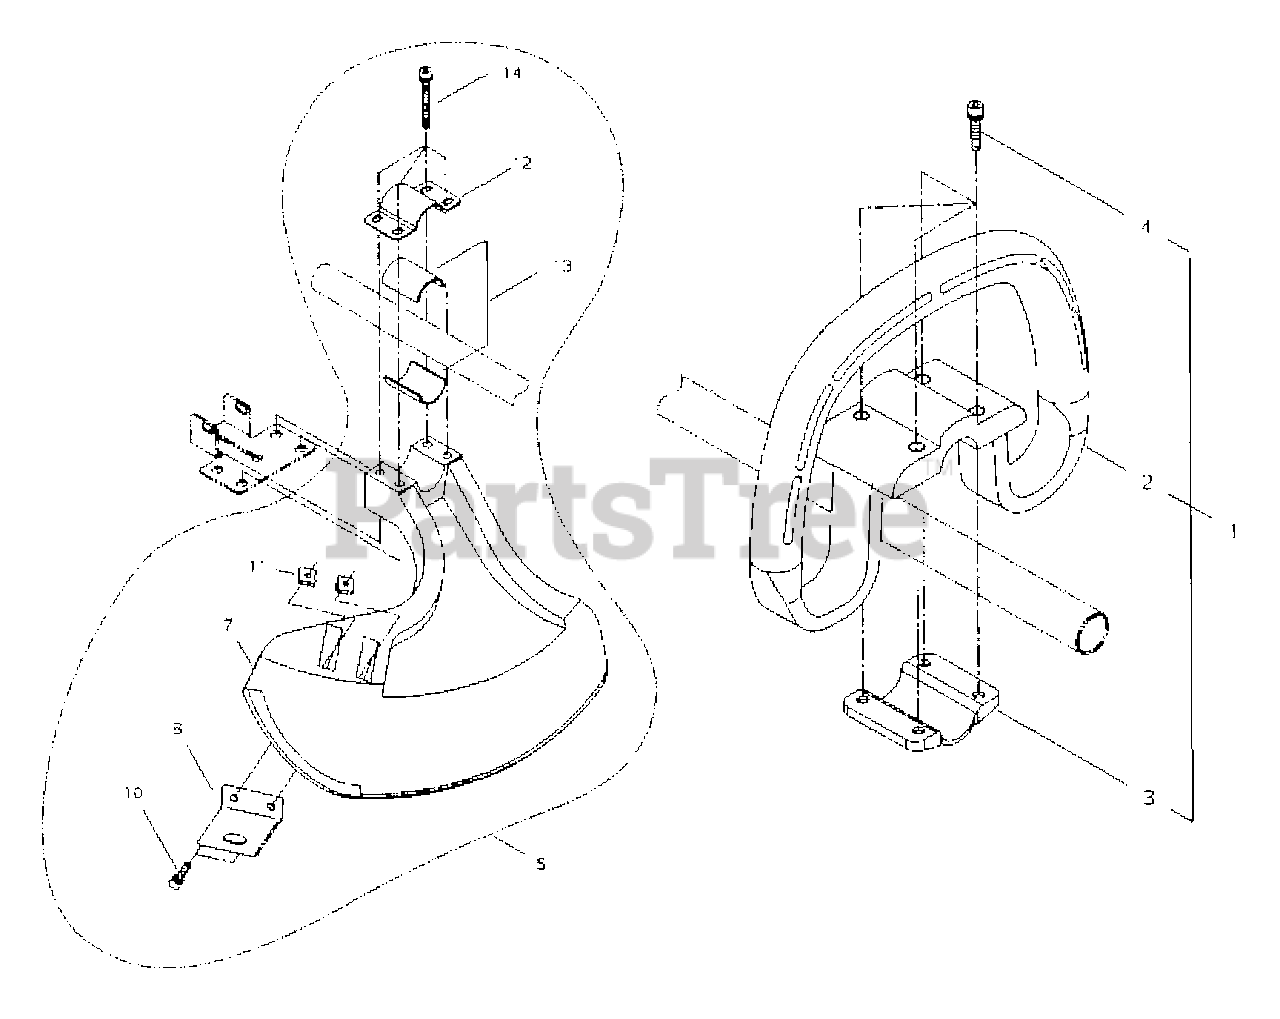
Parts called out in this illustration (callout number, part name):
1	HANDLE ASSY
2	HANDLE, SUPPORT
3	BRACKET, MOUNTING
4	BOLT M5×25
5	DEBRIS SHIELD KIT
7	SHIELD
8	CUTTER
10	BOLT M5×16
11	NUT M5
12	CLAMP, UPPER
13	SPACER
14	BOLT M5×45
